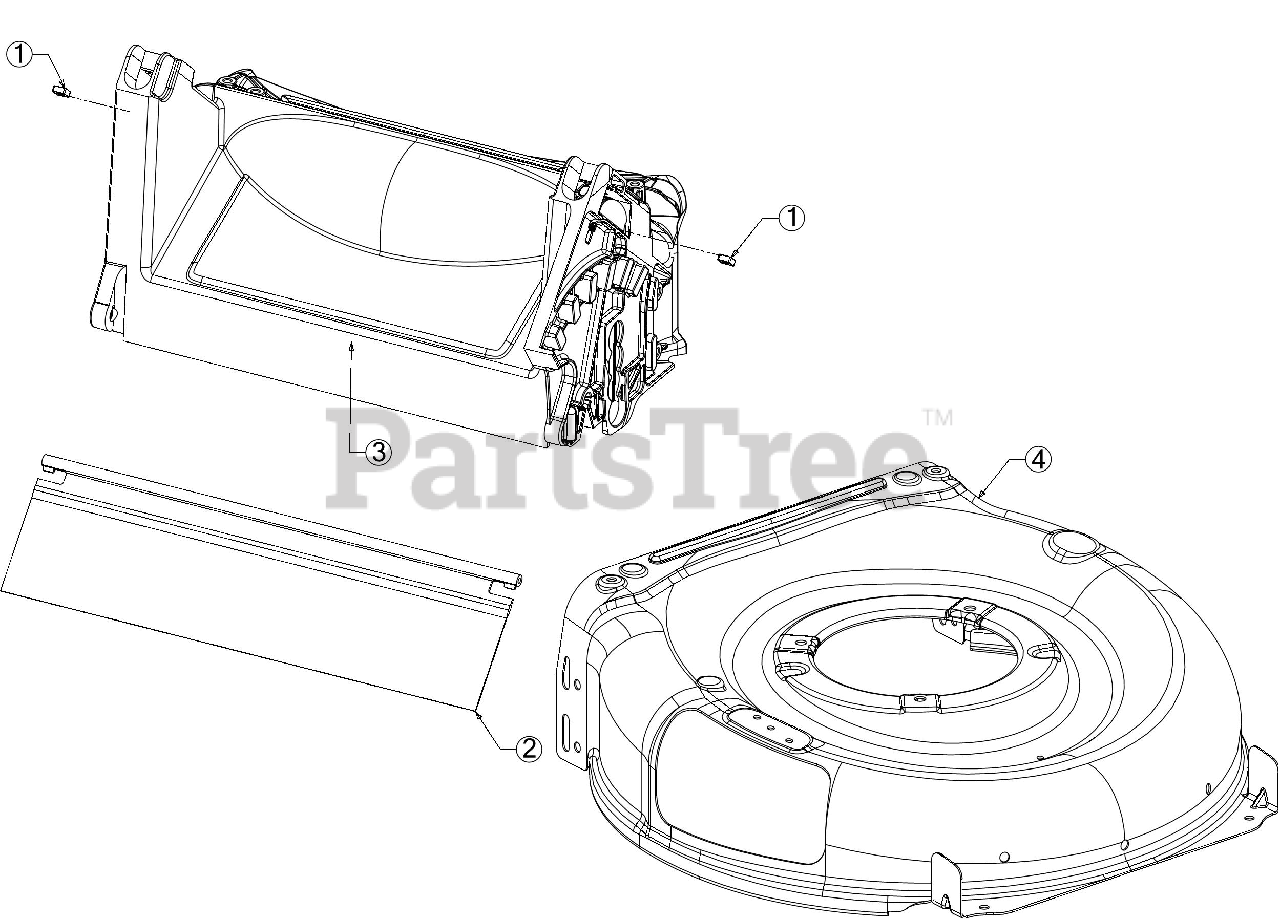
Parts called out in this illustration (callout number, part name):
1	SQUARE NUT 1/4-20
2	TRAILSHIELD
4	21" DECK (3N1)
